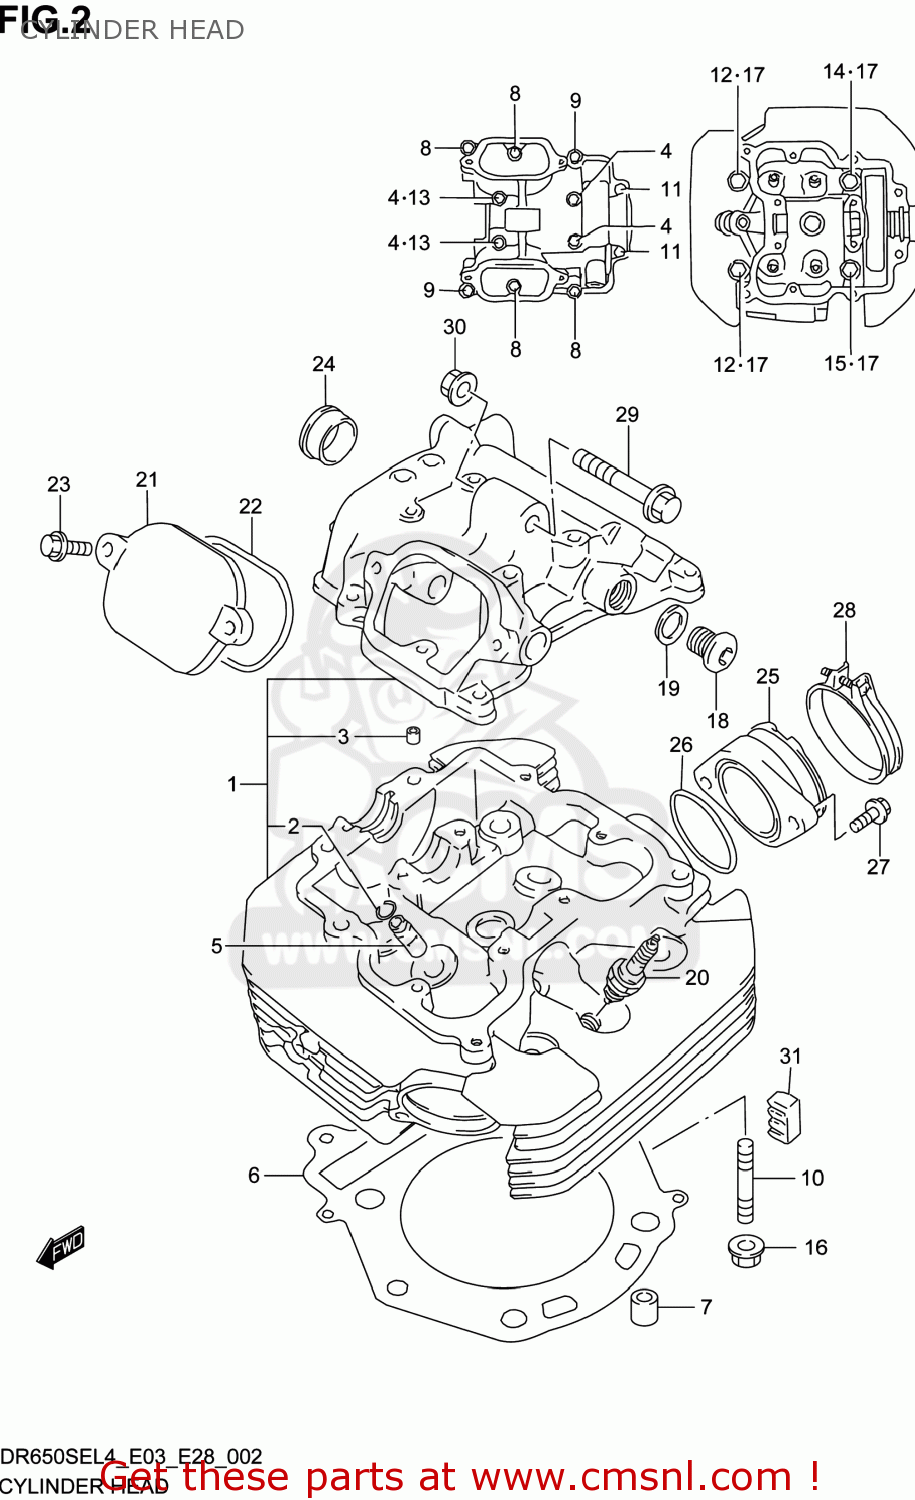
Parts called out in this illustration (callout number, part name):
1	HEAD ASSY,CYLINDER
2	RING,SNAP
3	PIN(6.2X8X11)
4	BOLT(6X55)
5	GUIDE,VALVE
6	GASKET,CYLINDER HEAD
7	PIN
8	BOLT
9	BOLT
10	BOLT,STUD
11	BOLT(6X115)
12	BOLT(10X180)
13	GASKET(5.8X13X1.2) (NAS)
14	BOLT(10X190)
15	BOLT(10X200)
16	NUT
17	GASKET(10.5X22X2) (NAS)
18	PLUG,14X12
19	GASKET(13.8X18.8X4.8) (NAS)
20	PLUG,SPARK(CR10E)
21	CAP,INSPECTION
22	O RING,INSPECTION CAP
23	BOLT
24	PLUG,OD:30
25	PIPE,INTAKE
26	O RING(D:2.4,ID:45.7)
27	SCREW(6X16)
28	CLAMP
29	BOLT(8X53)
30	NUT
31	PAD,CYLINDER HEAD RUBBER
